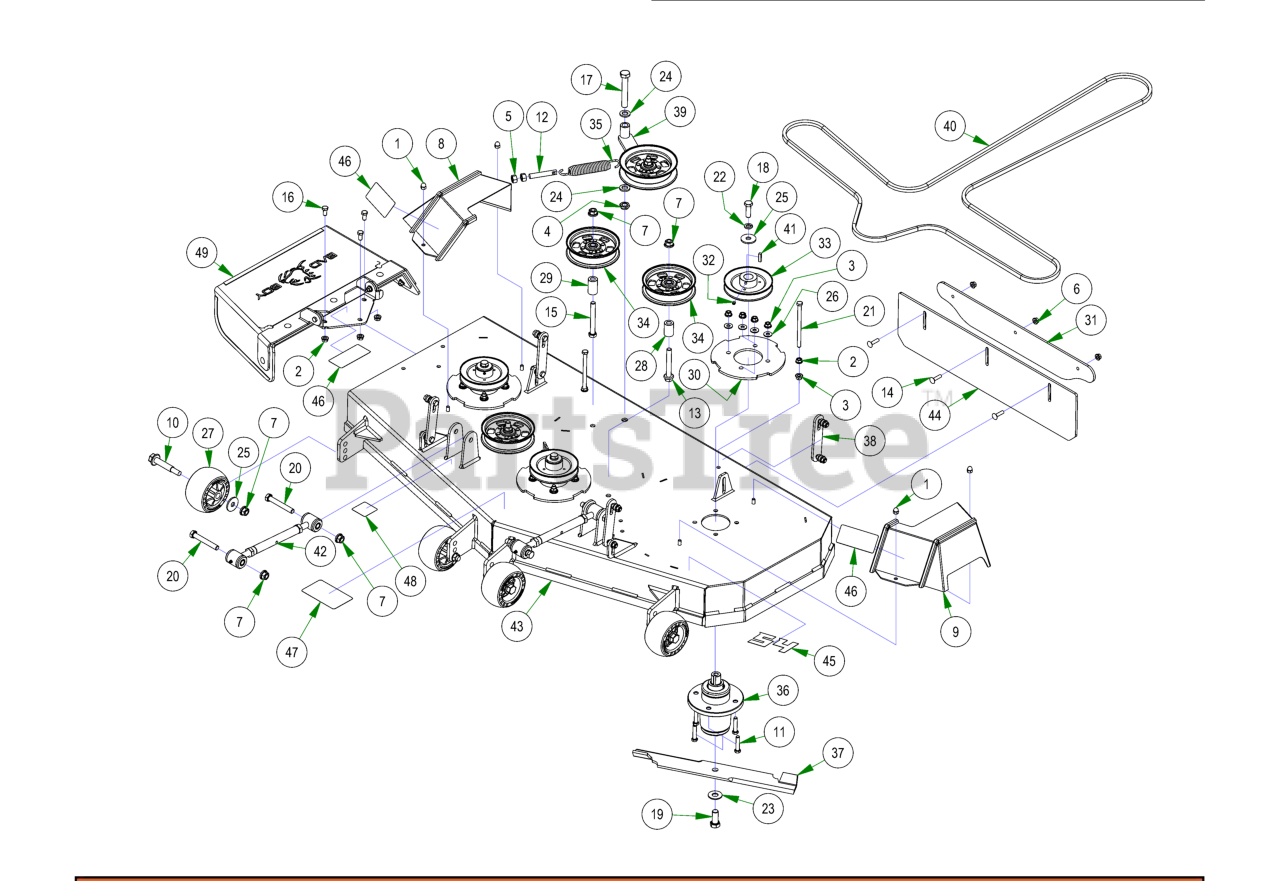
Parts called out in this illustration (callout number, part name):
1	5/16-18 ACORN NUT HIGH-CROWN ZC
2	3/8-16 HEX SERRATED FLANGE NUT HARD/ZINC
3	3/8-16 NYLON INSERT FLANGE LOCKNUT (GR.F) ZINC
4	5/8-11 NYLON INSERT JAM LOCKNUT ZINC
5	1/2-13 HEX NUT ZINC
6	5/16-18 NYLON INSERT FLANGE LOCKNUT ZINC
7	1/2-13 NYLON INSERT FLANGE LOCKNUT ZINC
8	2021 Maverick 54”/60” RH Pulley Cover
9	2021 Maverick 54”/60” LH Pulley Cover
10	Deck Wheel Bolt
11	3/8-16 X 1-3/4 HEX C/S (GR.5) ZC
12	All Thread
13	1/2-13 X 3-1/2 HEX FLANGE BOLT (GR.8) ZINC
14	5/16-18 X 1-1/4 CARRIAGE BOLT ZINC
15	1/2-13 X 4 HEX CAP SCREW (GR.8) ZINC YELLOW
16	3/8-16 X 3/4 HEX CAP SCREW (GR.5) ZINC
17	5/8-11 X 4 HEX CAP SCREW (GR.8) ZINC YELLOW
18	1/2-20 X 1-1/2 HEX CAP SCREW (GR.5) ZINC
19	5/8-18 X 1-1/2 HEX CAP SCREW (GR.8) ZINC YELLOW
20	1/2-13 X 3-1/2 HEX CAP SCREW (GR.5) ZINC
21	3/8-16 X 5-1/2 HEX CAP SCREW (GR.5) ZINC
22	1/2 SPLIT LOCKWASHER (GR.8) ZINC/YELLOW
23	5/8 USS FLAT WASHER (1-3/4" OD) GR.8 ZINC YELLOW
24	.635 ID X 1.120 OD X .140 THICK FLAT WASHER NYLON
25	1/2 BELLEVILLE WASHER (1-5/8 OD X .140 THK) ZINC
26	5/16 USS FLAT WASHER (7/8 OD) ZINC
27	Deck Wheel
28	.502 ID X .750 OD X 1.500 Long Spacer
29	1 3/4" Pulley Spacer
30	Deck Spindle Support Plate
31	2023 4" & 5" Stripping Kit Plate
32	5/16-24 X 1/4 SOCKET SET SCREW (CUP PT) PLAIN
33	5.25" Deck Spindle Pulley
34	5-3/4 Idler Pulley
35	Deck Idler Spring
36	OUTLAW SPINDLE ASSEMBLY
37	54" Fusion Blade for Avenger/ZT/Mav/Outlaw/Revolt
38	Deck Hanger Assembly
39	2017 MZ/ZT Deck Idler Assembly
40	B155.75 Deck Belt
41	1/4 X 1 SQ MACHINERY KEY 1018 STL PLN
42	2018 Maverick Turnbuckle (Top Link)
43	2023 54" x 5" Deck
44	2023 ZT Stripping Kit Rubber
45	54" Deck Decal
46	Danger Decal-Spindle/Discharge
47	Deck Belt Route Decal
48	Deck Impact Patent Decal 9591803
49	Discharge Chute Assembly
